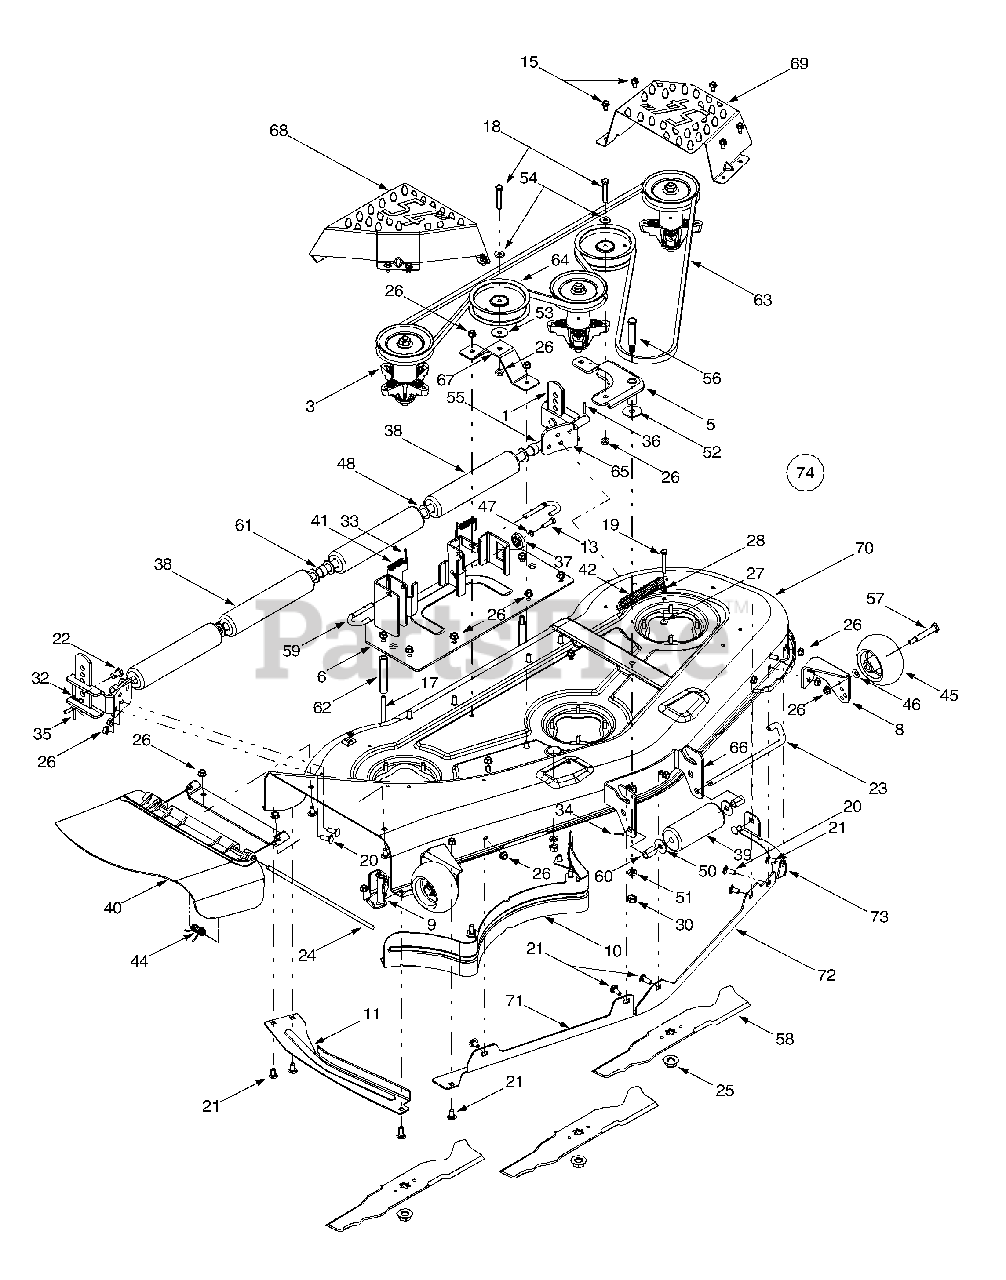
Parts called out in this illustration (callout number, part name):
1	Bracket, Adjustment, Height
2	Bracket, Hook, Retainer
3	Spindle Assembly, Pulley, 5.39 Dia x .
5	Idlr Assembly, 54"
6	Bracket Assembly, Lift, 54"
7	Bracket Assembly, LH-Front
8	Bracket Assembly, RH-Front
9	Stop Assembly, Chute
10	Baffle, RR, Inner
11	Guard, Finger
13	Hex Screw, 5/16-18, 1.25, Gr5,
14	Screw, Self-tapping, 5/16-18, 1.000
15	Screw, Self-tapping, 5/16-18, 0.625
16	Hex Screw, 1/4-20, .620, Gr5,
17	Screw, Carriage, 3/8-16, Gr5, 5.00
18	Hex Screw, 3/8-16, 2.25, Gr5,
19	Hex Screw, 5/16-18, 2.25, Gr5,
20	Bolt, Carriage, 3/8-16 x 1.0
21	Short Neck Carriage Bolt 3/8-16 x .75
22	Pin, Clevis, .50 Dia x .78
23	Pin, Roller, .5" Dia x 10.06
24	Pin, Hinge, Dia .375 x 14.06
25	Nut, Hex Flange, 5/8-18
26	Nut, Flange Lock, 3/8-16
27	Nut, Flange Lock, 5/16-18, Gr5
28	Nut, Hex, 5/16-18, Gr5
29	Nut, Hex, 7/16-14, Gr2
30	Nut, Hex Lock, 1/2-13
31	Nut, 1/4-20, Hexflg, Lock
32	Pin, Click, .092 x 1.64
33	Pin, Cotter, 1/8 x 1.25
34	Pin, Cotter, 3/32 x 1.25
35	Pin, Sprg, 1/4 Dia x 1.00
36	Pin, Spring, 3/16 x 1.25
37	Adjustment, Deck, Gear
38	Roller, Deck
39	Front Roller
40	Deflector, Chute
40	Bracket, Chute
41	Spring, Compression, .406 x .531 x 1.75
42	Spring, Extension, .94 Dia x 6.74
43	Spring, Extension, 1.15 Dia x 5.99
44	Torsion Spring .44 I.d. x 2.10
45	Deck Wheel, 5" Dia.
46	Washer, Bell, .375 x .870 x .063
47	Washer, Lock, 5/16, Regular Duty
48	Flat Washer, .812 ID x 1.38 OD x .1
49	Washer, Lock, 7/16 , Regular Duty
50	Flat Washer, .51 ID x 1.5 OD x .07
51	Washer, Lock, 1/2 , Regular Duty
52	Flat Washer, .531 x 1.75 x .090
53	Flat Washer .406 ID X 1.5 x 11ga
54	Washer, Flat .38 ID x.93 OD x.110
55	Roller Shaft, .750 x .47.12
56	Shoulder Screw, 5/8 Dia x 2.50
57	Shoulder Screw, 1/2 Dia x 2.50
58	Blade, 18.50"
59	Deck Release Handle Rod, .375 Dia
60	Spacer .550 ID x .755 OD x 1.1
61	Spacer, .82 ID x 1.00 OD x .53
62	Spacer, .405 x .75 x 3.875
63	Belt, V-Type, B Section
64	Pulley, Idler, 5.0 Dia.
65	Bracket, Mounting, 54" Roller
66	Bracket, Roller, Front
67	Bracket, Idler
68	Cover, Spindle RH
69	Cover, Spindle LH
70	Deck Shell Assembly, 54"
73	LH Extension Skirt
74	54-inch Deck Assembly Complete
